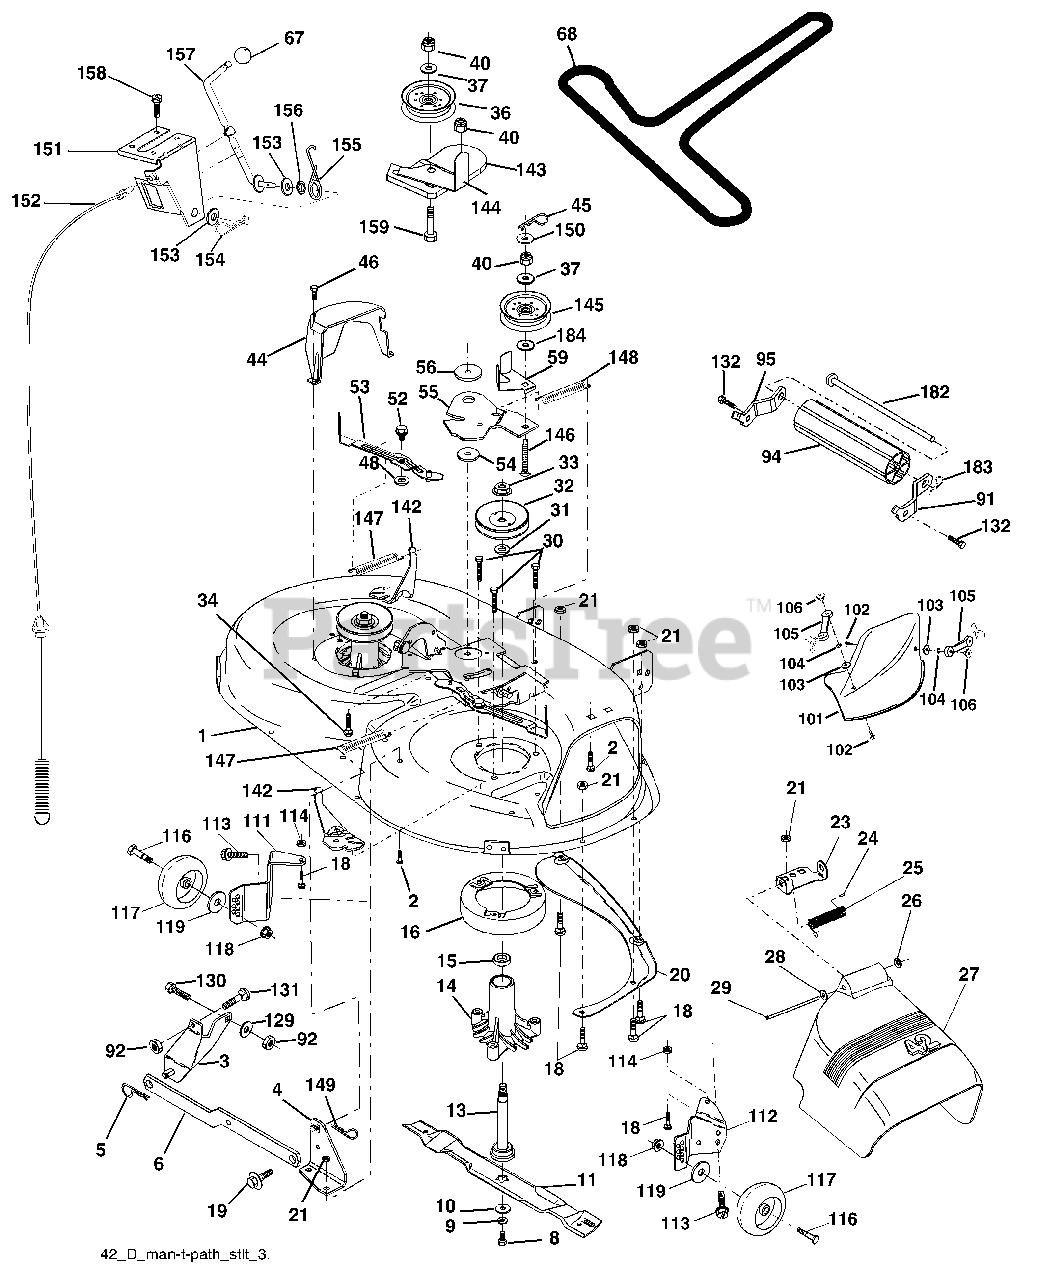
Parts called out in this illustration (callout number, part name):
1	Deck Asm MWR 42"weldment
2	Bolt Rdhd Sqnk 5/16-18unc X3/4
3	Bracket Asm Fr Sway Bar 38/42
4	Bracket Asm Deck 42"sway Bar
5	Retainer Spring
6	Deck Sway Bar
8	Bolt 3/8 - 24 X 1.25 Gr 8
9	Washer Lock Hvy 3/8
10	Washer Hard Blade Mower Vented
11	Blade, 42" Mulching Std
11	Blade, 42" Mulching Premium
11	Blade, 42" Hi-Lift
13	Shaft Asm W/lower Bearing
14	Housing Mandrel Vented
15	Bearing Ball Mandrel
16	Stripper Mower
18	Bolt Rdhd Sqnk 5/16-18 X 5/8
19	Bolt Shoulder
20	Baffle Vortex 42
21	Nut Crownlock 5/16-18 UNC
23	Bracket Deflector Mower 42"
24	Cap Sleeve 80x 112 Blk Mower
25	Spring Torsion Deflector 2 52
26	Nut Push Phos & Oil
27	Shield Deflector Mower 42" Blk
28	Washer 11/32 X 5/8 X 16 Ga
29	Rod Hinge 42"6 75 Wlg
30	Screw Thd Rolling
31	Washer Spacer Mower Vented
32	Pulley Mandrel 42"
33	Nut Toplock Flng
34	Bolt Rdhd 3/8-16uncx1-3/4 Gr5
36	Pulley Idler Flat 3 060
37	Washer 13/32 X 13/16 X 16
40	Nut Crownlock 3/8-16 UNC
44	Guard Mandrel LH Black
45	Spring Retainer 1" Zinc/cad
46	Screw Hex Thd Cut 1/4-20 x 5/8 T
48	Washer Hardened Smaller
52	Bolt Shoulder 5/16-18 Unc Blkz
53	Arm Asm Pad Brake
54	Washer Hardened
55	Arm Idler 42"mower LT/YT
56	Spacer Retainer Mower
59	Guard TUV Idler
67	Knob Rd 3/8-16 Plstc Thds Blk
68	V-Belt Mower 42"
91	Bracket Roller Nose LH
92	Nut Lock Hex w/Ins. 3/8-16 Unc
94	Roller Nose
95	Bracket Roller Nose RH
101	Cover Mulch 42"
102	Screw Pan Head Phillip 10-24 x 5/8
103	Washer #10
104	Washer Lock #10
105	Latch Asm. Mulch
106	Nut Weld #10-24
111	Bracket Wheel Gauge LH 42" Deck
112	Bracket Gauge Wheel RH 42" Deck
113	Screw Tapping 3/8-16 x .625
114	Nut Keps 5/16-18 Unc
116	Bolt Shoulder
117	Wheel Gauge
118	Nut Centerlock 3/8-16 UNC
119	Washer 3/8 x 7/8 x 14 Ga.
129	Washer 13/32 x 13/16 x 12 Ga.
130	Bolt Rd Hd Sqnk 3/8-16 Unc x 1
131	Bolt Fin Hex 3/8-16 Unc x 1 Gr. 5
132	Screw Hex Wsh Thdr. 3/8-16 x 3/4
142	Arm Spring Brake Mower
143	Bracket Arm Idler 42"
144	Keeper Belt 42" Clutch
145	Pulley Idler Flat
146	Bolt Carriage Idler
147	Spring Extension
148	Spring Return Idler
149	Retainer Spring Yellow
150	Washer 9/32 x 3/4 x 16 Ga.
151	Bracket Clutch Cable
152	Clutch Cable 42"
153	Washer Flat 3/8" Type B
154	Spring Retainer
155	Spring Retention Lvr Cltch Cab
156	Spacer Clutch Cable
157	Rod Clutch Cable 3/8"
158	Screw Hex Thd Cut 1/4-20 x 1/2
159	Bolt Rdhd Sqn 3/8-16 Unc x 1-3/4
182	Rod Roller Nose
183	Retainer Spring
184	Washer 13/32 x 7/8 x 10 Ga.
